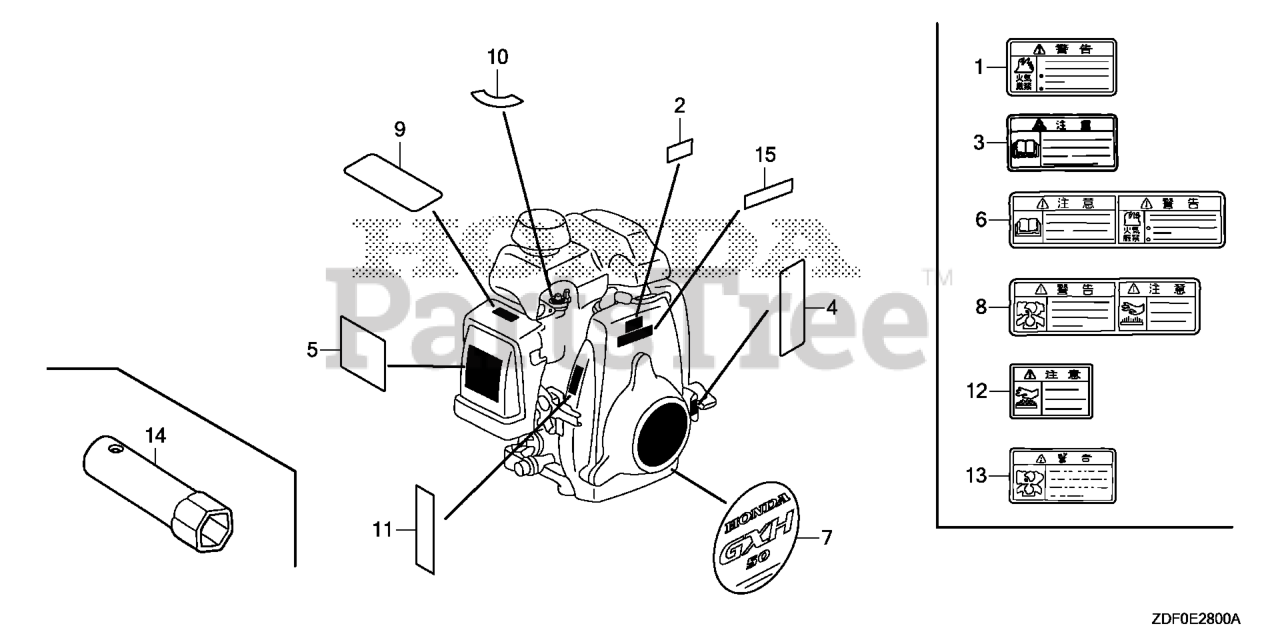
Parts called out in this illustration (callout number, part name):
5	MARK, OPER CAUTION
10	MARK, PETCOCK (EXTERNAL)
14	WRENCH, SPARK PLUG
